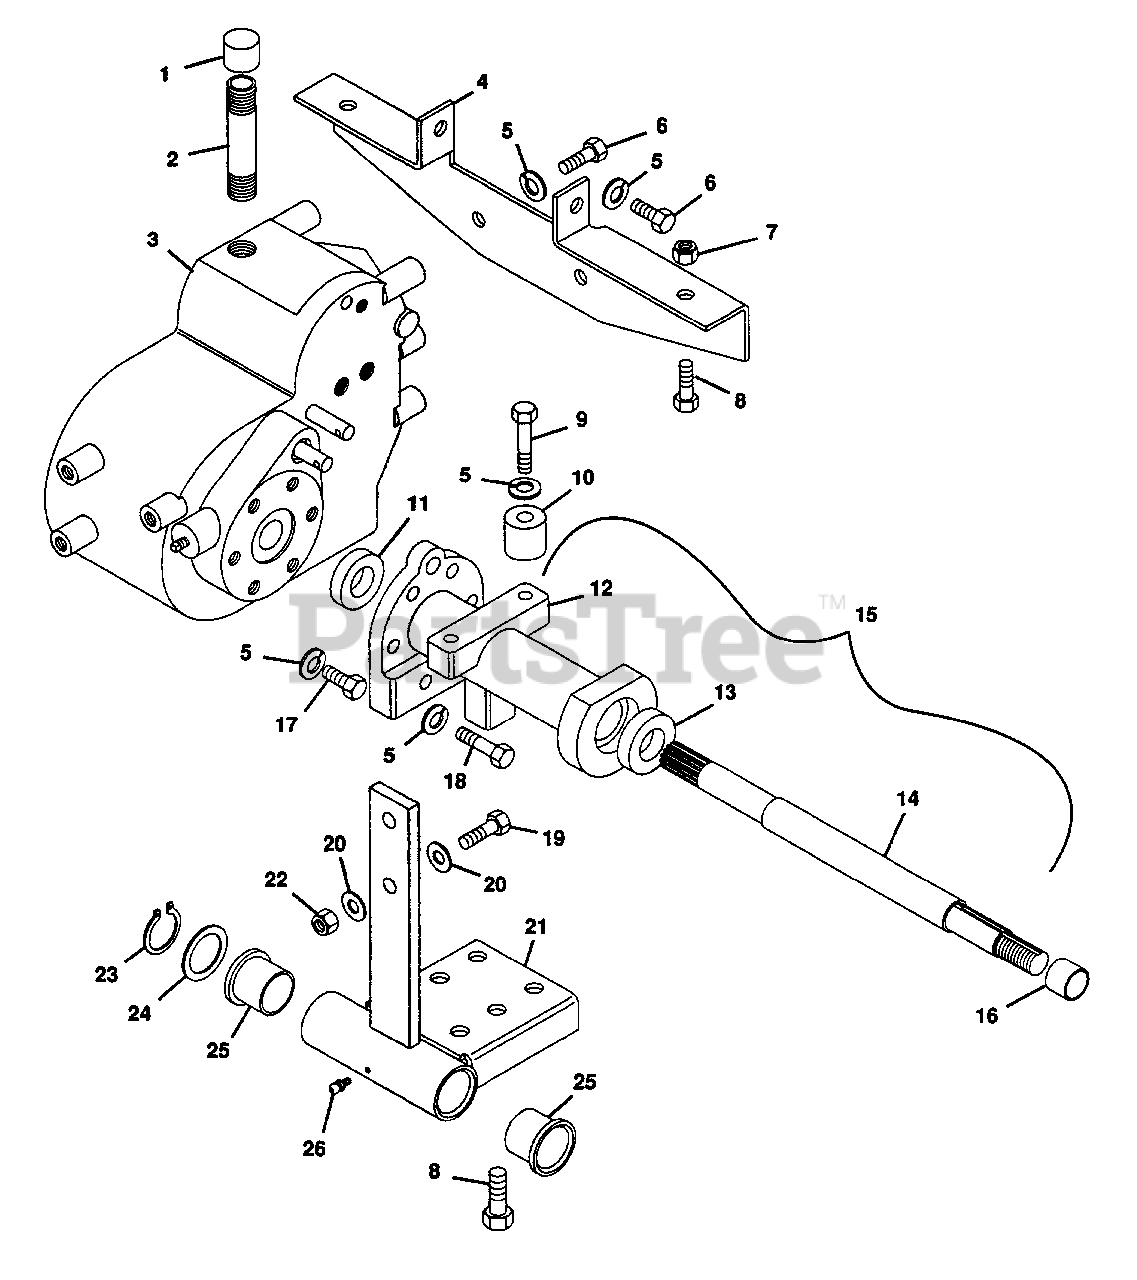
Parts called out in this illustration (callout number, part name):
1	Cap, Pipe 3/4 NPT Plain
2	Nipple, Pipe 3/4 NPT x 5 Plain
3	Transaxle
3	Transaxle(Differential Lock)
4	Plate, Transaxle
5	Washer, Lock 1/2 Reg.
6	Bolt, Hex 1/2-13x1.25
7	Nut, Lock 5/8-11
8	Bolt, Hex 5/8-11x1.50
9	Bolt, Hex 1/2-13x2.75
10	Spacer, Frame
11	Ring, Alignment
12	Housing, Axle
13	Bearing, Ball 1.181x2.440x.629
14	Axle
15	Assembly, Axle Housing
16	Bush., St. 1.19x1.38x.800 Stl.
17	Bolt, Hex 1/2-13x1.50
18	Bolt, Hex 1/2-13x2.25
19	Bolt, Hex 1/2-13x1.75
20	Washer, Flat .531x1.062x.095
21	Weldment, Pivot Bracket
22	Nut, Lock 1/2-13
23	Ring, Retaining
24	Bearing, Thrust Race
25	Bearing, Flanged Nylon
26	Fitting, Lube 1/4-28
